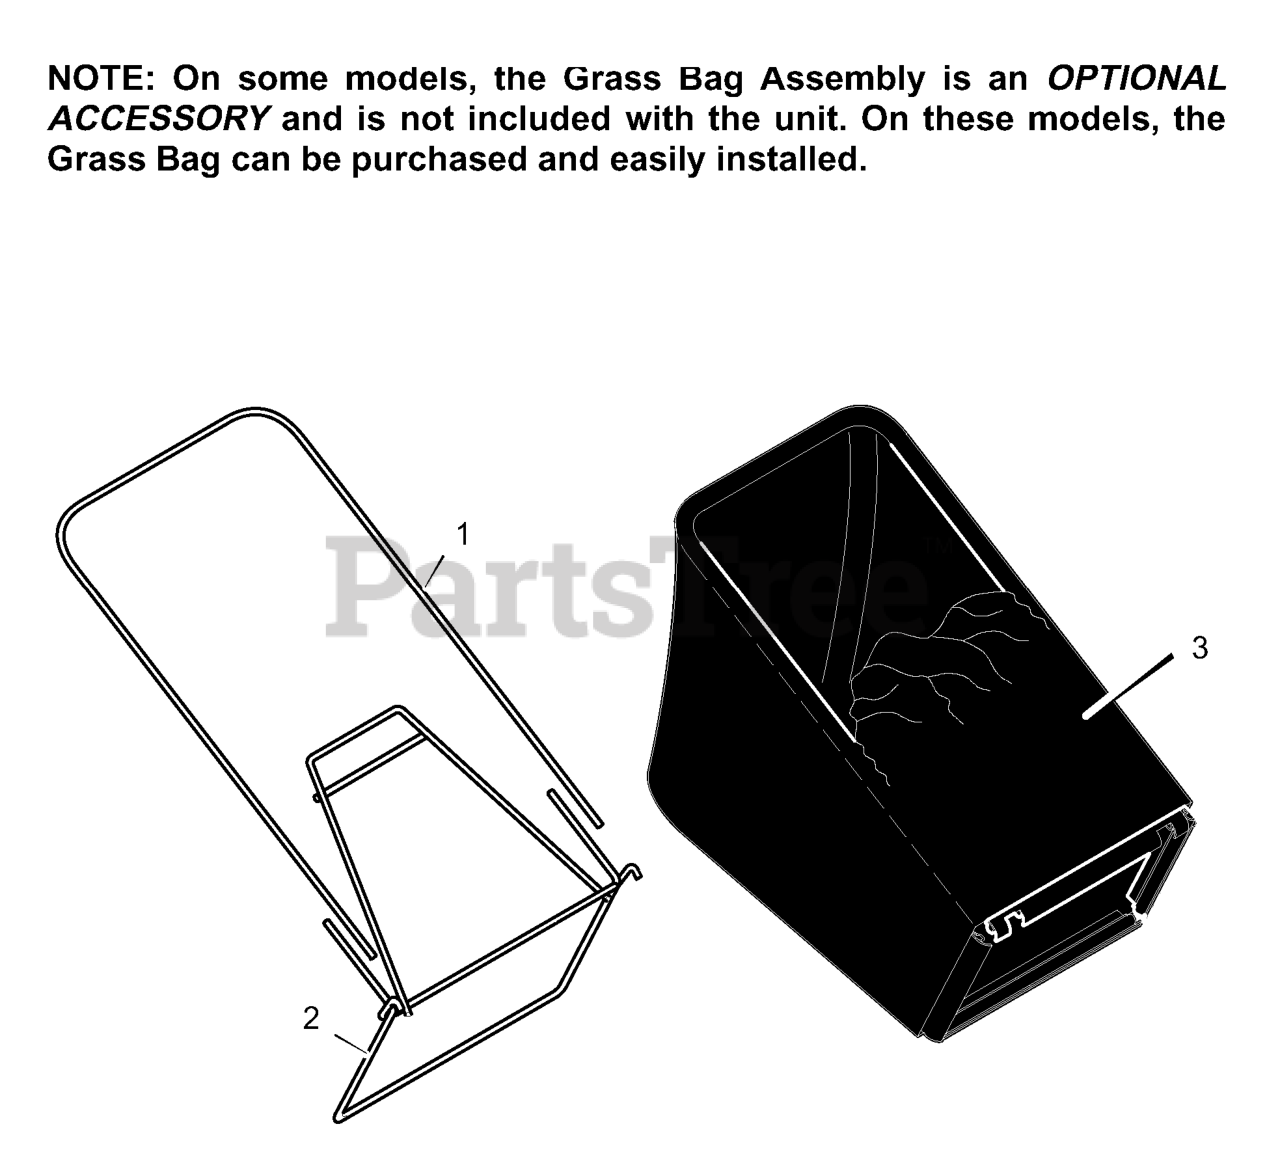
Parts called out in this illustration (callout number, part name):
1	Frame, Top
2	Frame Assembly
3	Bag, Cloth - Gray
